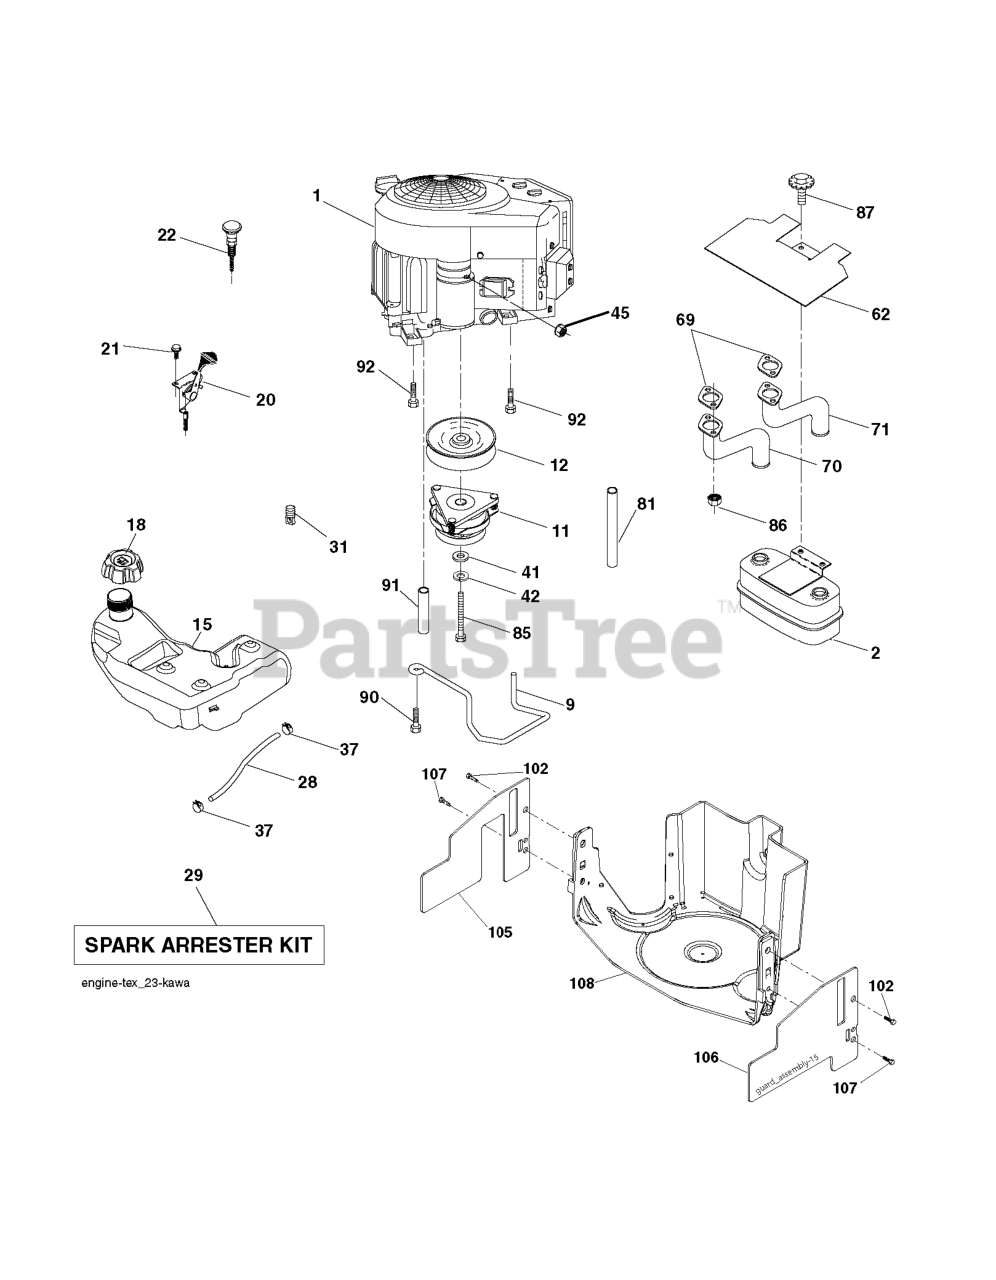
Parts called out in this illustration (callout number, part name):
2	MUFFLER.TWIN.CYL.LOW.TONE
9	KEEPER.BELT.ENGINE.4.2
11	RB.CLUTCH.OGURA.4.4.PD
12	PULLEY.ENGINE.TUFFTORQ
15	TANK.FUEL.4GAL
18	CAP.FUEL.TANK.3"GREY
20	THROTTLE CABLE
21	SCREW
22	CONTROL.CHOKE.ERGO.PUSH-IN.BLA
28	REPL BY 532 00 85-43
29	KIT.SPARK ARRESTOR 794945 B&S
37	HOSE CLAMP
42	LOCKWASHER
45	NUT
62	RP SHIELD HEAT MUFFLER
70	EXHAUST TUBE LH KAWI
71	EXHAUST TUBE RH KAWI
81	TUBE, DRAIN OIL ASM.
85	BOLT HEX 7/16-20X4-1/4"
86	NUT.HEX.FLANGE.TOPLOCK
87	BOLT.5/16-18UNCX1.W/SEMS.BLK
90	SCREW 3/8-16X1
91	BUSHING.1.375OD
92	SCREW 3/8-16X1
102	SCREW
105	SHIELD.SIDE.LH.3842"TEX FRENCH
106	SHIELD.SIDE.RH.3842"TEX FRENCH
107	SCREW.1/4-20X5/8
